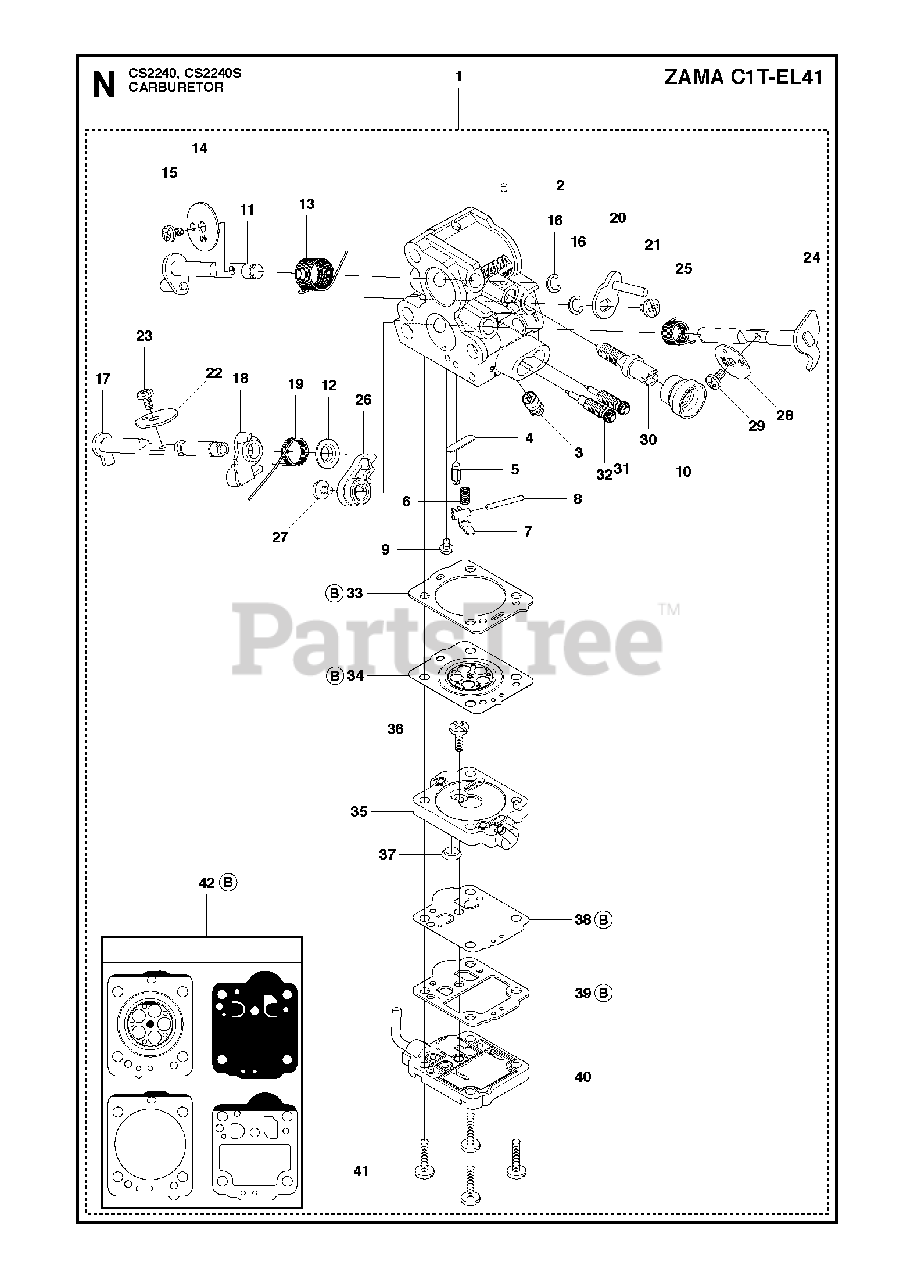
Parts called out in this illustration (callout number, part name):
1	CARBURETOR
2	PLUG
3	NOZZLE ASSY
4	PLUG
5	INLET NEEDLE
6	SPRING
7	LEVER
8	PIN FULCRUM
9	SCREW
10	CAP ZAMA 0051034
11	SHAFT ASSY
12	COLLAR ZAMA 005020
13	SPRING
14	VALVE
15	SCREW
16	CIRCLIP
17	SHAFT ASSY
18	LEVER
19	SPRING
20	LEVER
21	SCREW
22	VALVE
23	SCREW
24	SHAFT ASSY
25	SPRING
26	LEVER
27	SCREW
28	VALVE
29	SCREW
30	SCREW
31	SCREW
32	SCREW
33	GASKET
34	DIAPHRAGM
35	BODY
36	SCREW
37	STRAINER
38	DIAPHRAGM
39	GASKET
40	COVER
41	SCREW
42	GASKET KIT
